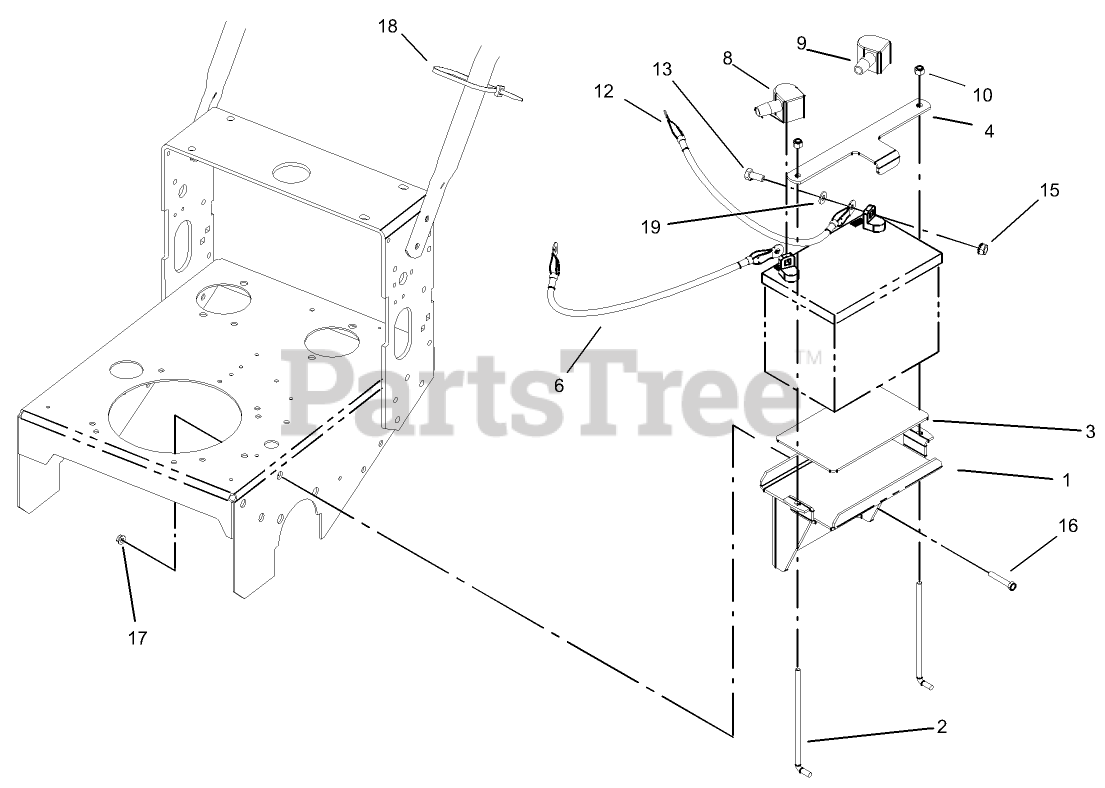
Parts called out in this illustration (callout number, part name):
1	BATTERY PLATE ASM
2	HOLDOWN-BATTERY
3	PAD-SKID, ANTI
4	PLATE-HOLD DOWN, BATTERY
6	CABLE-BATTERY, BLACK
8	BOOT-TERMINAL, BLACK
9	BOOT-TERMINAL, RED
10	NUT-LOCK, NI
12	CABLE-BATTERY, RED
13	SCREW-HH
15	NUT-KEPS
16	SCREW-HHF
17	NUT-HF
18	TIE-CABLE
19	WASHER-FLAT
